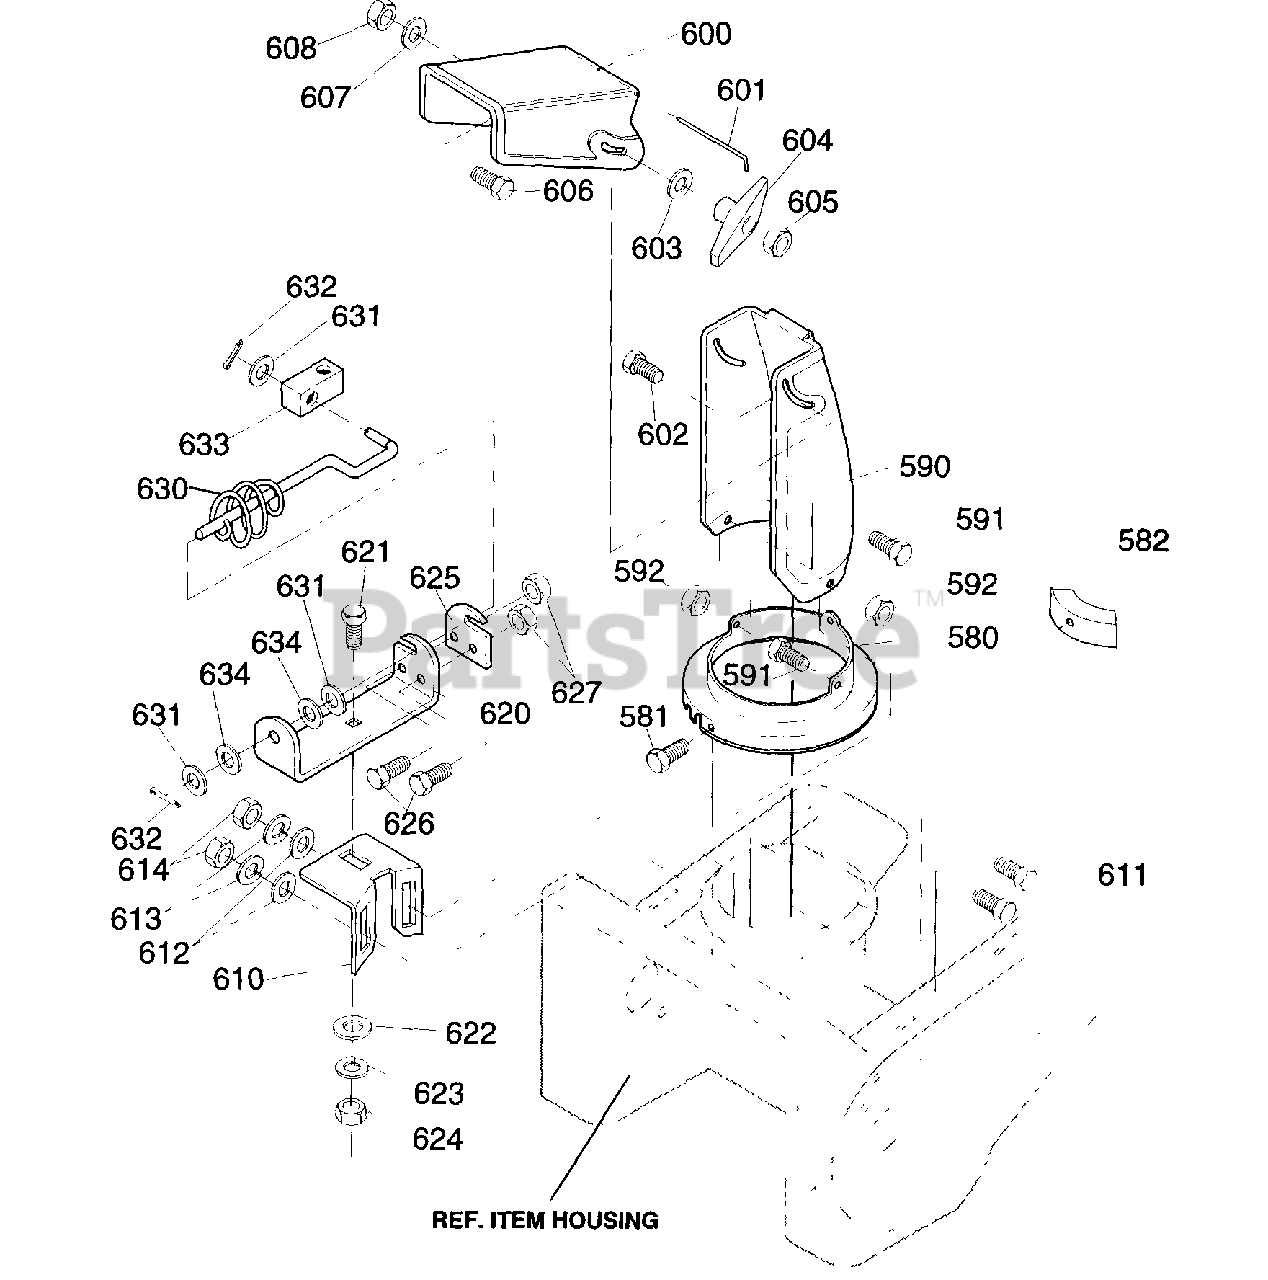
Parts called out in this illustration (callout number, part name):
580	RING, LOWER CHUTE
581	SCREW, 1/4-14 X .63 HWATAP
582	CLIP, CHUTE RING PLASTIC
590	CHUTE, LWR SRS 8HP
591	SCREW, 1/4-20 X .50 HHC
592	NUT, 1/4-20 WDFL MAC-LOCK
600	CHUTE, UPR SRS W/OHDLE
601	WIRE, HINGE 6.65 LG SR
602	BOLT, 5/16-18 X 1.25 CARR
603	WASHER, FLAT .344 X .69 X .065
604	NOB, T 2BLADE W/516/18 NUT
605	NUT, 5/16-18 REGHEX
606	SCREW, 5/16-18 X .75 SLTRMA
607	WASHER, FLAT .344 X .69 X .065
608	NUT, 5/16-18 REGHEXCTRLK
610	BRACKET, WORM ADJUST
611	BOLT, 5/16-18 X .75 CARR
612	WASHER, FLAT .344 X .69 X .065
613	WASHER, HVSPTLK
614	NUT, 5/16-18 REGHEXCTRLK
620	BRACKET, CHUTE ROD HOLDER
621	BOLT, 5/16-18 X .75 CARR
622	WASHER, FLAT 344 X .69 X .065
623	WASHER, HVSPTLK
624	NUT, 5/16-18 REGHEXCTRLK
625	PLATE, CHUTE ROD
626	SCREW, 1/4-20 X .50 HHC
627	NUT, 1/4-20 REGHEXCTRLK
630	ROD, ASSY CHUTE LWR
631	WASHER, FLAT .40 X .75 X .025
632	PIN, COTTER .090 DIAX .75 LG
633	BLOCK, PIVOT PLASTIC
634	WASHER, CURVED SPRING
